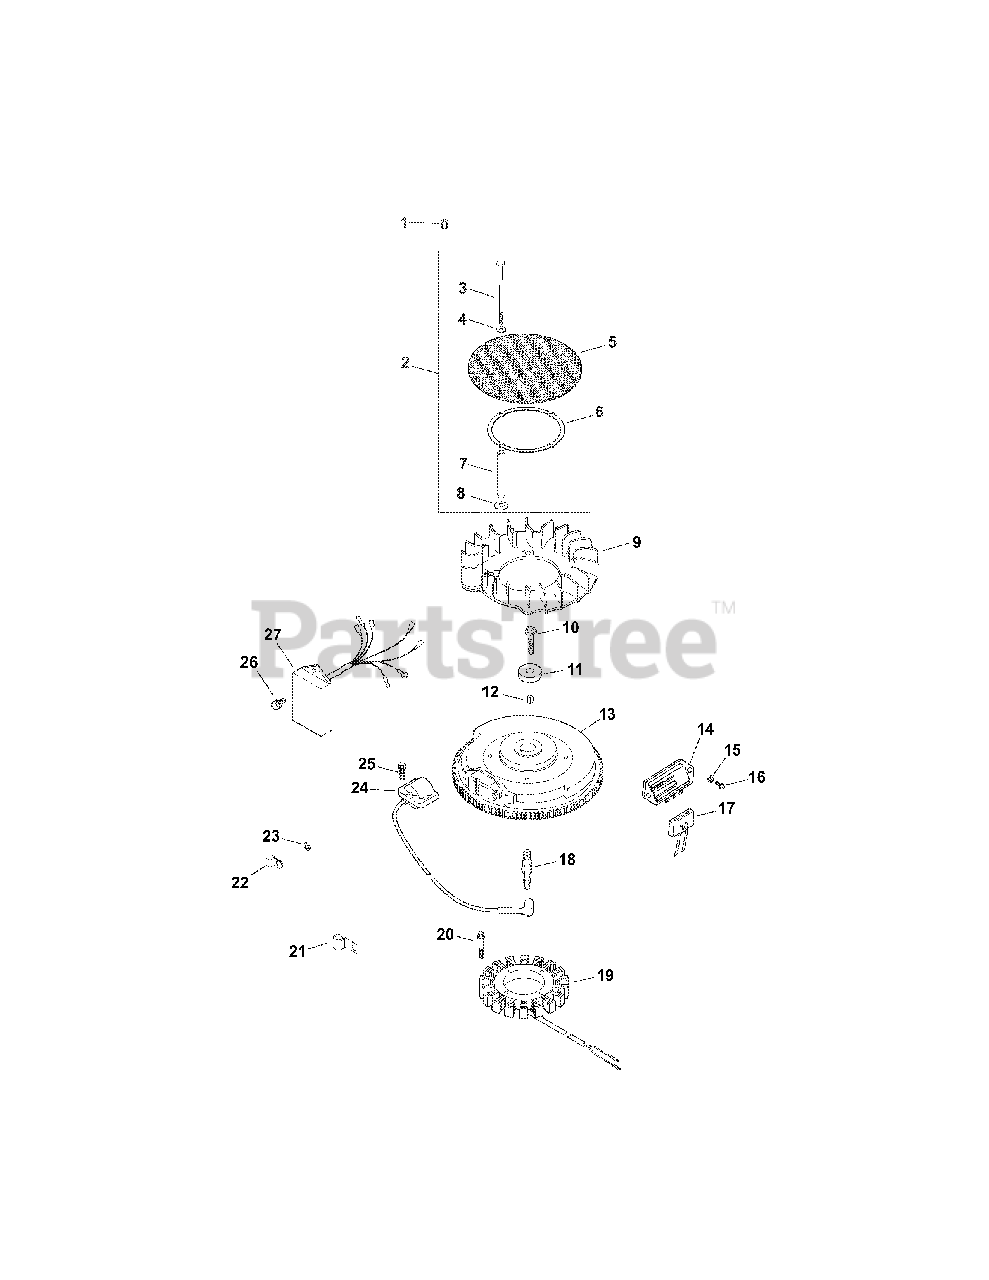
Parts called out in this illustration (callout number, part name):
1	Screw, skt set #10-24x1/4 inch
2	Kit, chopper screen (Includes 3-8, KH-41- 037-10-S)
3	Screw, cap M6x1.0x99.5
4	Washer, flat 1/4"
5	Screen, grass
6	Ring, support
7	Spacer, grass screen
8	Washer, spring 10 mm
10	Screw, flg M10x1.5x45
11	Washer, flat 3/8"
13	Flywheel
14	Rectifier-regulator
15	Washer, flat 3/16"
16	Screw, phl hd #11-16x7/8 inch
17	Connector (3 contact)
18	Spark Plug
19	Kit, 15 amp stator
20	Screw, thd frm M5x0.8x25
22	Clamp, insulated
23	Washer, flat 1/4"
24	Module, ignition
25	Screw, flg thd frm M5x0.8x20
26	Screw, thd frm M4x0.7x10
27	Module, speed advance
